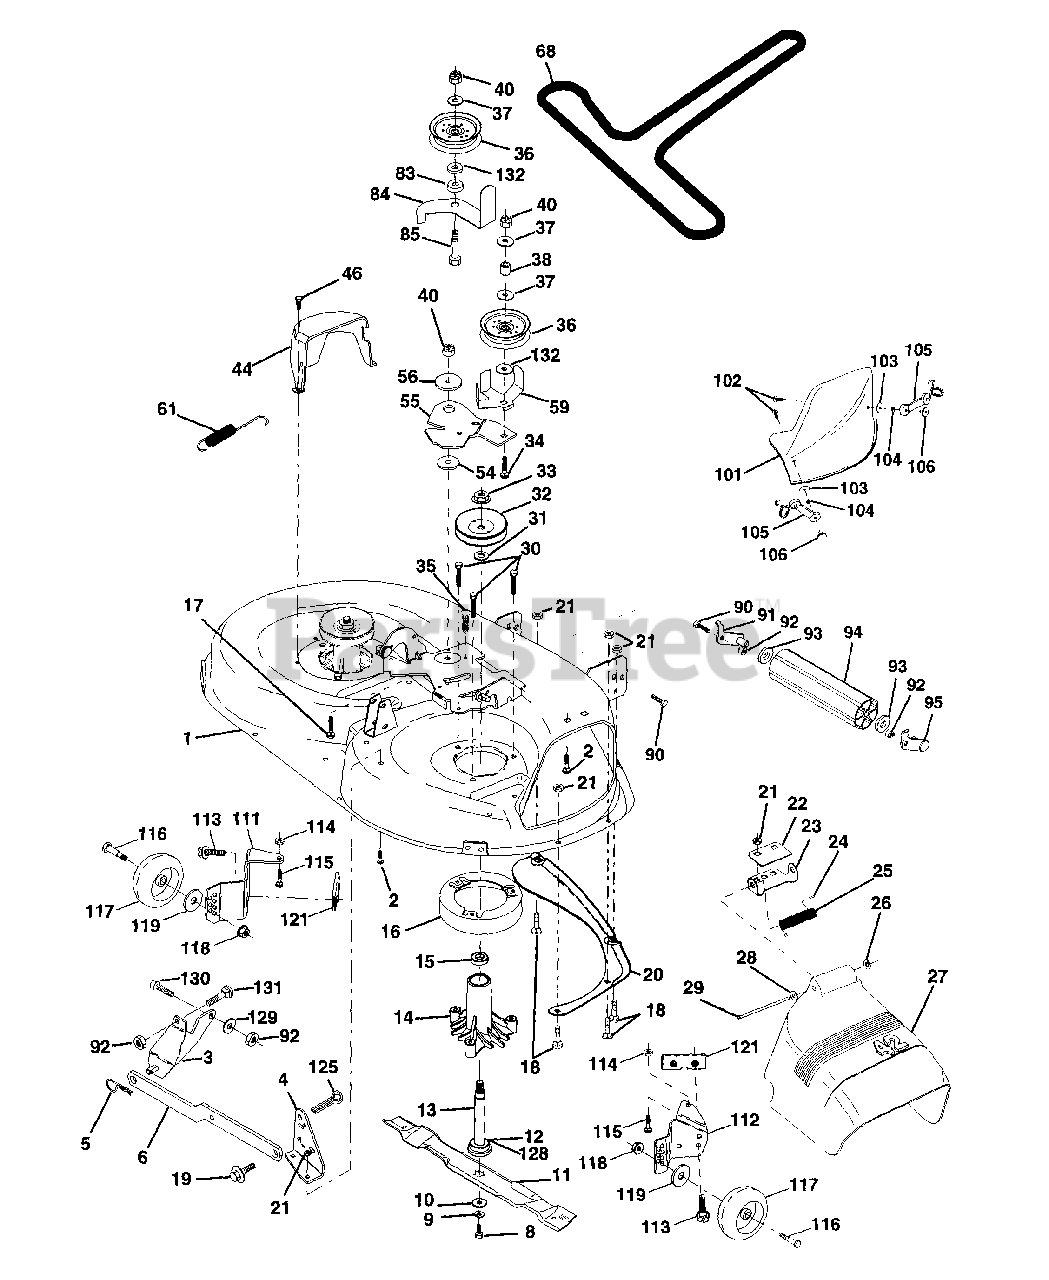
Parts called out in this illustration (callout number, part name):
1	Housing Asm Mower 42"94 T-Path
2	Bolt Rdhd Sqnk 5/16-18unc X 3/4
3	Bracket Asm Fr Sway Bar 38/42
4	Bracket Asm Deck 42"sway Bar
5	Retainer Spring
6	Arm Suspension Rear
8	Bolt 3/8-24 x 1 25 Gr8 Patched
9	Washer Lock Hvy 3/8 Unplated
10	Washer Hard Blade Mower Vented
11	Blade Mower Mulching 42"
12	Bearing Ball #6204 (Mandrel)
13	Shaft Asm W/lower Bearing
14	Housing Mandrel Vented(machd)
15	Bearing Ball Mandrel
16	Stripper Round Mower
17	Bolt Rdhd Sqnk 3/8-16 X 2-1/4
18	Bolt Carr 5/16-18 X 5/8
19	Bolt Shoulder
20	Baffle Vortex 42
21	Nut Crown Lock 5/16-18
22	Stiffener Bracket 42"deck
23	Bracket Deflector Mower 42"
24	Cap Sleeve 80 x 112 Blk Mower
25	Spring Torsion Deflector 2 52
26	Nut Push Phos & Oil
27	Shield Deflector Mower 42" Blk
28	Washer 11/32 X 5/8 X 16 Ga
29	Rod Hinge 42"6 75 Wlg
30	Screw Thdrol Hex Hd Zinc Mwr.
31	Washer Spacer Mower Vented
32	Pulley Mandrel 42"
33	Nut 9/16top Lock Flng Cntr
34	Bolt RDHD 3/8-16 UNC x 2-3/4 Gr5
35	Fastner Christmas Tree
36	Pulley Idler Flat 3 060
37	Washer 13/32 X 13/16 X 16 Ga
38	Spacer Spring Stop Idler
40	Nut Lock 3/8-16 Unc
44	Guard Mandrel LH Black
46	Screw Thdrol 1/4-20 x 5/8
54	Washer Hardened
55	Arm Idler 42 "mower LT/YT
56	Spacer Retainer Pm Mower
59	Guard, Belt
61	Spring Ext. Elect
68	V-Belt Mower
83	Washer Sintered
84	Keeper Belt Idler
85	Bolt Carriage 3/8-16 x 2-1/4 Gr.5
90	Bolt Fin Hex 3/8-16unc X 1
91	Bracket Asm Noseroller LH
92	Nut Lock Hex w/ins. 3/8-16 UNC
93	Washer 1 17/32 X 7/8 X 16 Ga
94	Roller Nose 38 & 42
95	Bracket Asm Noseroller RH
101	Cover Mulching 42" Blk
102	Screw
103	Washer #10
104	Washer Lock #10
105	Latch Asm Bagger
106	Nut Weld .327/.304 #10-24
111	Bracket Wheel Gauge Lh 42" Deck
112	Bracket Gauge Wheel Rh 42" Deck
113	Screw Thdrol 5/16-18 x 3/4 TYT
114	Nut Keps 5/16 - 18 UNC
115	Bolt Carriage 5/16 - Unc x 1/2
116	Bolt Shld
117	Wheel Gauge Donut
118	Nut Centerlock 3/8 - 16 UNC
119	Washer 3/8 x 7/8 x 14 Ga.
125	Cotter Pin
128	Washer Felt
129	Washer 13/32 x 13/16 x 12 Ga.
130	Bolt Fin Hex 3/8-16unc x 1 Gr. 5
131	Bolt Rdhd Sqnk 3/8-16 UNC x 1
132	Washer 13/32 x 1-3/8 x 3 Ga.
